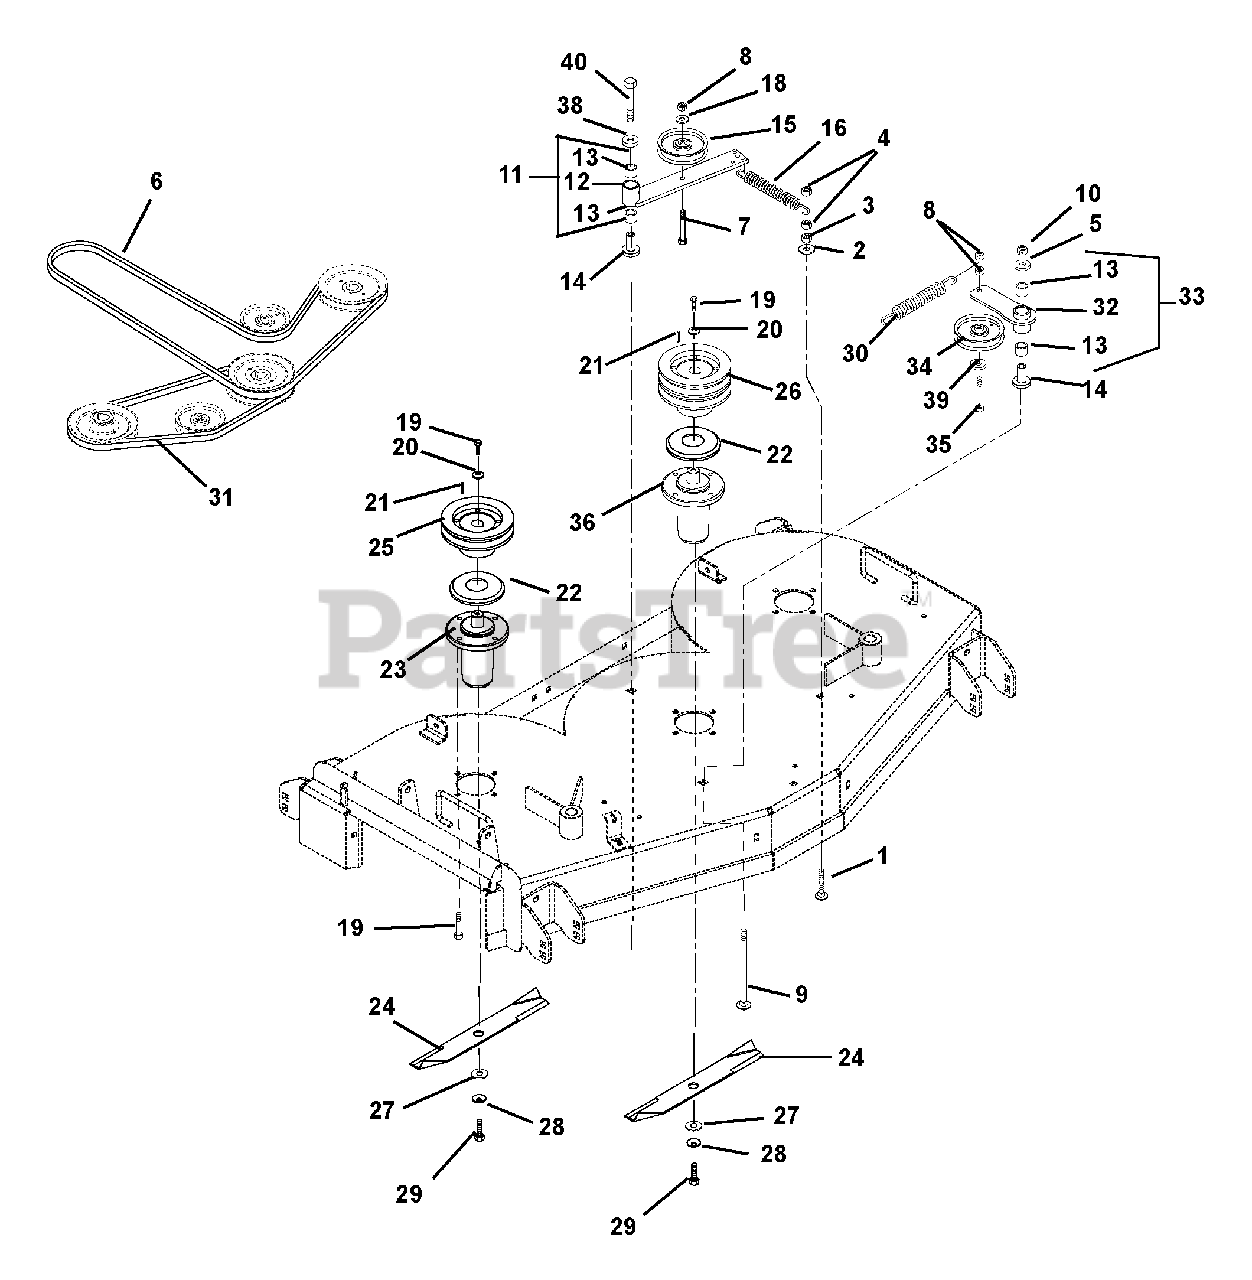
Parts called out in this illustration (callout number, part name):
1	@BLT-RDHDSQNK .38-16X1.50 G5YZ
2	@WSHR-LK .38X.094 REG YWZC
3	@NUT-HEX .38-16 YWZC
4	@NUT-LK-CTR .38-16 YWZC
5	WSHR-FL-STL .531X1.250X.10 YWZ
6	V-BELT, HB-WRAPPED
7	@BLT-RDHDSQNK .38-16X3.00 G5YZ
8	@NUT-LK-CTR .38-16 YWZC
9	@BLT-RHDSSQNK .50-13X3.50 G5YZ
10	@NUT-LK-CTR .50-13 YWZC
11	ASSEMBLY - IDLER PIVOT ARM
12	WMT - IDLER PIVOT ARM
13	BRG, 1.00 X 1.12 X .75
14	BEARING, PEDESTAL
15	IDLER-FLAT 4.00X.38 (2.00 W)
16	SPRING, EXTENSION
17	WSHR-FL-STL.755X1.375X.062YWZC
18	SEAL, IDLER BEARING
19	BLT-HEX .38-16X1.0 GR8 YZ EP30
20	WSHR,FLT STL.406X1.50X.245YWZC
21	KEY, SQ .25X.25X1.00 RC 40-50
22	SLINGER, DUST
23	ASM,MAINT FREE SPINDLE
24	BLADE, MULCH 16.25
25	WELDMENT, SPINDLE SHEAVE 5.00
26	SHEAVE, DOUBLE (5.25")
27	WSHR-FLT .640X1.75X.250 YWZC
28	WSHR-BLVL .669X1.535X.138
29	BLT-HEX .62-18X1.75 GR8 YWZC
30	SPRING, EXT
31	V-BELT, 5L-RAW EDGE
32	WMT, IDLER PIVOT ARM
33	ASM, IDLER PIVOT ARM
34	V-IDLER, 4.00X.38
35	@BLT-HEX .38-16X2.25 GR5 YWZC
36	ASM,MAINT FREE SPINDLE
37	@BLT-RDHDSQNK .50-13X3.75 G5YZ
38	WSHR-FL-STL .515X1.625X.250 YZ
39	@WSHR-FL-STL.406X.812X.065 YWZ
40	@BLT-HEX .50-13X3.75 GR5 YWZC
